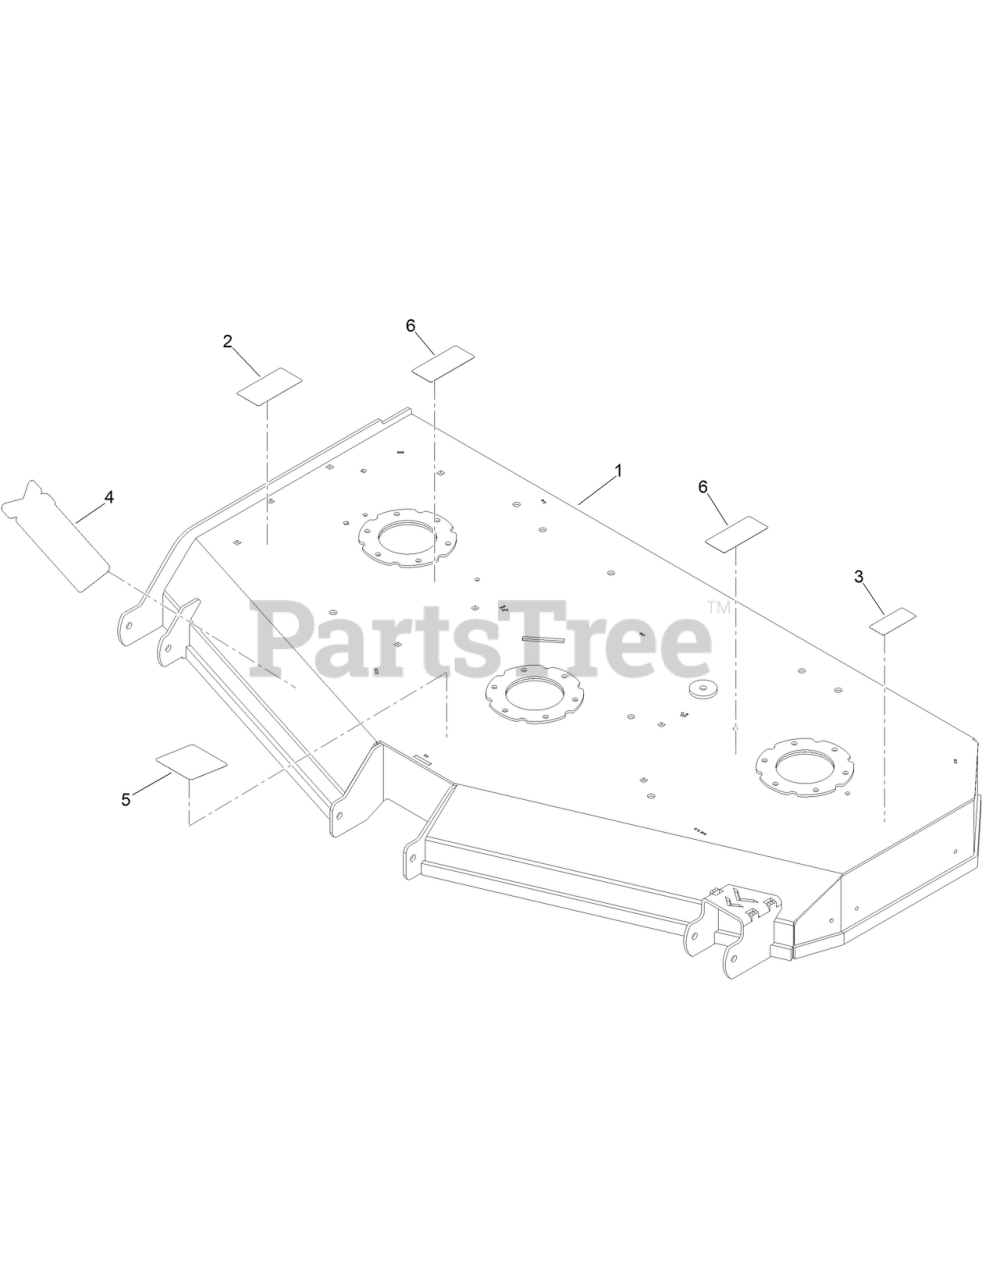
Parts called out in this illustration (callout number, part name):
1	DECK ASM-61 PAINTED
2	2020 XTF-61 DECAL
3	DECAL-DECK BELT ROUTING
4	DECAL-DANGER, DECK
5	DECAL-SAFETY BLADE TORQUE
6	DECAL-ROTATING FAN HAZARD
